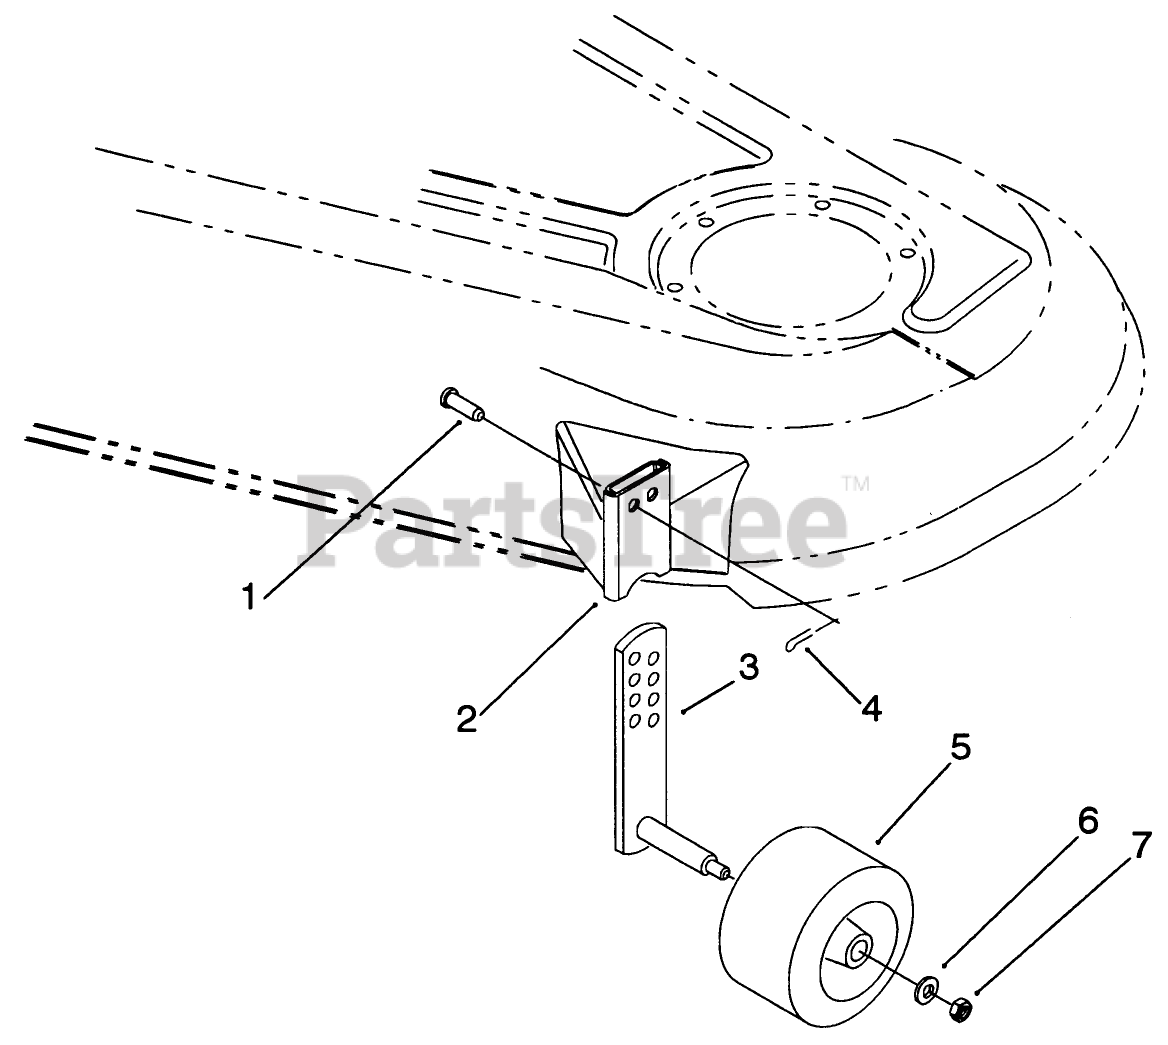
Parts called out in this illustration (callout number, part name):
1	PIN-CLEVIS
2	ROLLER SUPT WA R
3	GAGE-WHEEL
4	PIN-HAIR
5	WHEEL-GAGE
6	WASHER-FLAT
7	NUT-LOCK, NI
